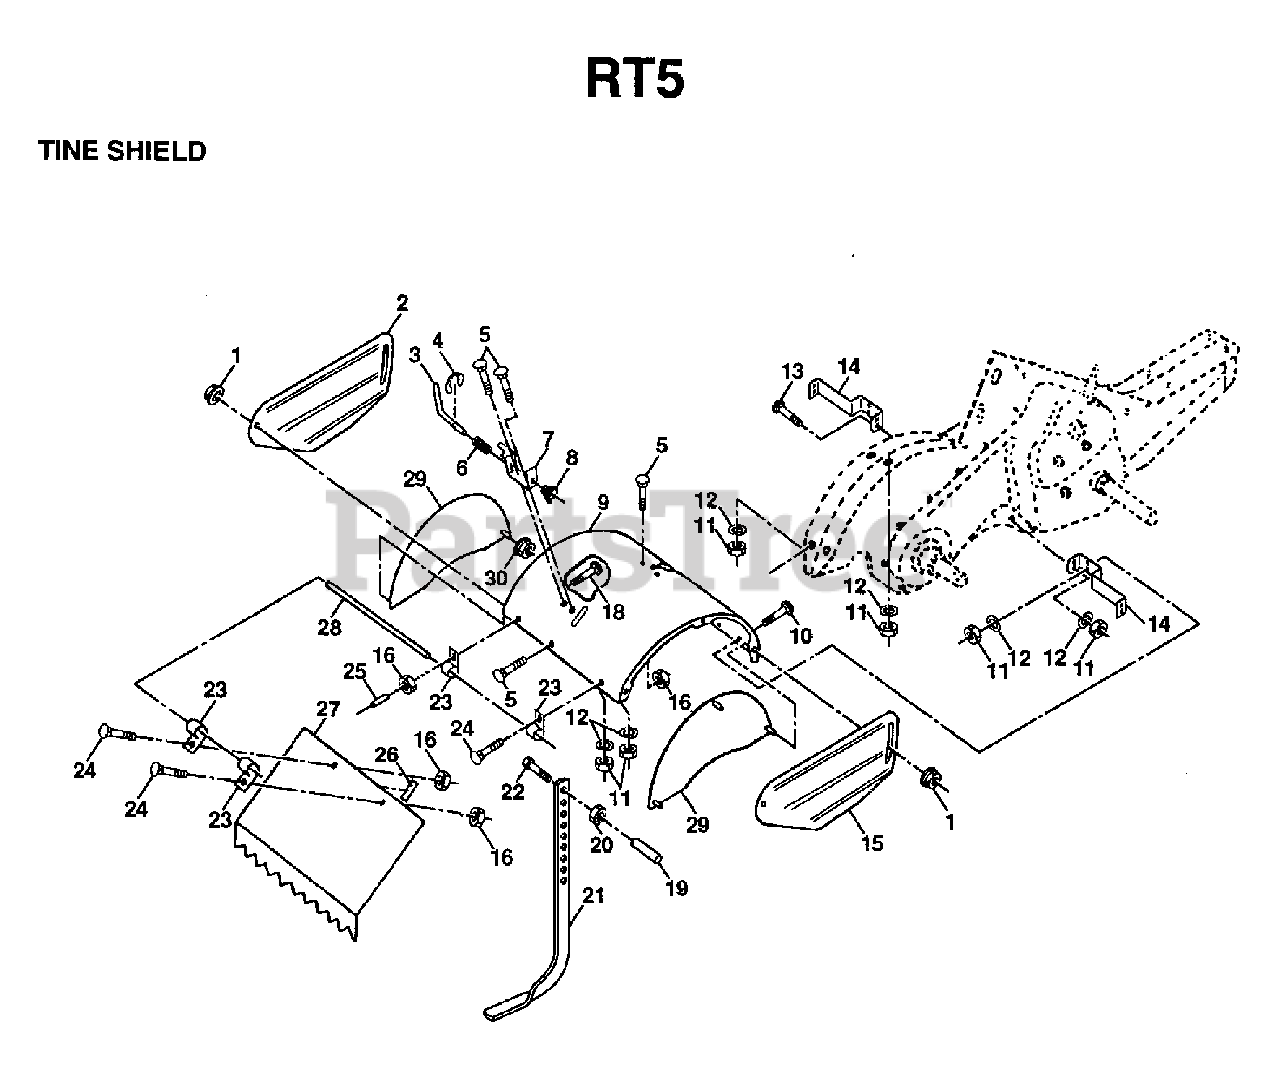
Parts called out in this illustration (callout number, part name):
1	NUT
3	STAKE PIN TI
4	KLIP RING TI
5	BOLT
6	SPRING TI
7	LATCH BRACKET TI
8	SPRING CRT
10	BOLT
12	LOCKWASHER
13	BOLT.CARRIAGE.5/16-18
14	BRACKET.TINE.SHIELD.TILLER
16	NUT
20	NUT.HEX.3/8-16UNC
21	STAKE DEPTH CRT
22	BOLT.375-16
23	HINGE CRT
25	VINYL CAP TI
26	PAD IDLER TI
28	PIN.HINGE.TILLER
30	LOCKNUT-FLANGE 5/16-18
